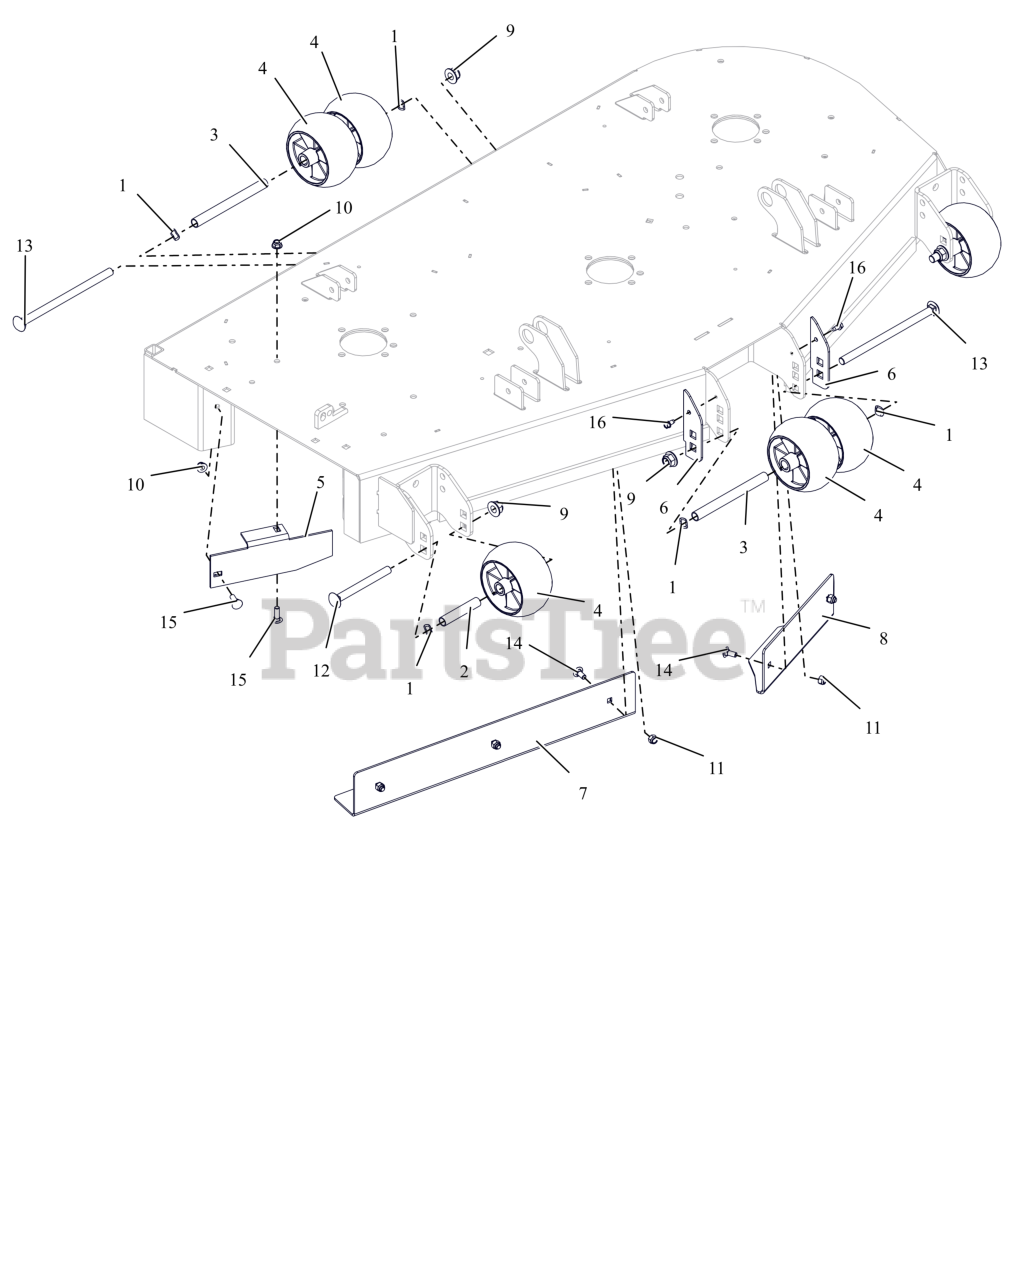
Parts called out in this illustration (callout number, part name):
1	WAVE WASHER .531X.781X.125FH
2	SPACER, .510X.625X3.35
3	SPACER, .510X.625X6.50
4	ANTI-SCALP WHEEL - 5X3 CTR
5	BAFFLE, DISCHARGE, 52"
6	PLATE, ANTI SCALP WHEEL EXT.CE
7	BAFFLE, 52" RH VACUUM (ORANGE)
8	BAFFLE, 52" LH VACUUM (ORANGE)
9	NUT,NYL-FLG .50-13 GF ZCC
10	NUT,LK-NYL-FLG .31-18 G5ZC120
11	NUT,NYL .31-18 G5 ZCC
12	BLT, RHSN .50-13X5.00 G5 ZCC
13	BLT, RHSN .50-13X8.50 G5 ZCC
14	BLT,RHSN .31-18X.75 G5 ZCC
15	BLT,RHSN .31-18X1.00 G5 ZCC
16	SCR-TAP .25-20X.50 HWH ZCC
